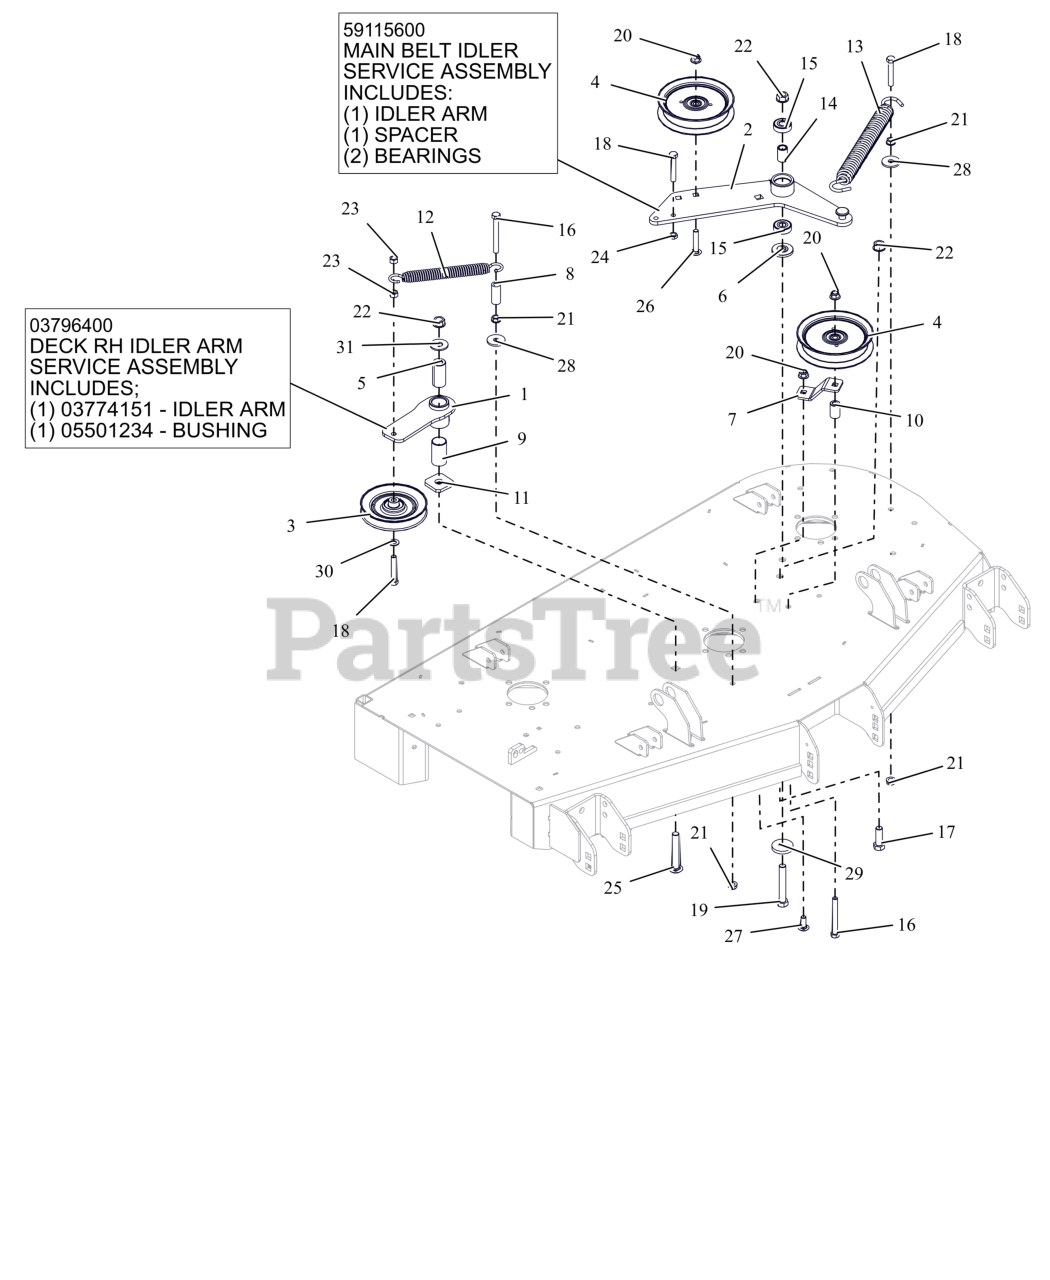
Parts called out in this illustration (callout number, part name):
1	WMT, IDLER ARM - BLACK
1	ASM, IDLER ARM (DECK)
2	WLDMT, DECK PTO IDLR ARM
2	ASSEMBLY, MAIN BELT IDLER
3	IDLER, V-5.00"
4	IDLER, FLAT 5.00"
5	BSHG, SPCR .502X.997X2.03 PM
6	SPACER, IDLER ARM
7	PTO FIXED IDLER MTG BRKT -RED
8	HOSE, .38 X 1.65
9	BSHG, 1.00X1.125X1.937
10	BUSHING, SLV .380X.750X1.190
11	WSHR-FLT .640X1.75X.250
12	SPRING, EXTENSION
13	SPRING, EXTENSION
14	SPACER .510 X .75 X 1.1485
15	BRG-BALL .500X1.38X.437
16	BLT, HEX .38-16X3.25 G5 ZCC
17	BLT,HEX .50-13X1.50 G5 ZCC
18	BLT,HEX .38-16X2.25 G5 ZCC
19	BLT,HEX .50-13X3.25 G5 ZCC
20	NUT,NYL-FLG .38-16 GF ZCC
21	NUT, SPNLK-FLG .38-16 G5 ZCC
22	NUT-LK-CTR-FLG .500-13 GG ZCC
23	NUT-LK-CTR .38-16 ZC120
24	NUT-JAM .375-16 G2 ZCC
25	BTL,RHSSN .500-13 X 3.25 G5 ZCC
26	BLT,RHSSN.375-16X2.00 G5 ZCC
27	BLT,RHSSN .38-16X1.00 G5 ZCC
28	WSHR,FLT .406X1.375X.135 ZCC
29	WSHR-FL-STL 0.557X1.625X0.25 ZCC
30	WSHR,FLT .406X.812X.065 ZCC
31	WSHR,FLT .563X1.375X.109 ZCC
